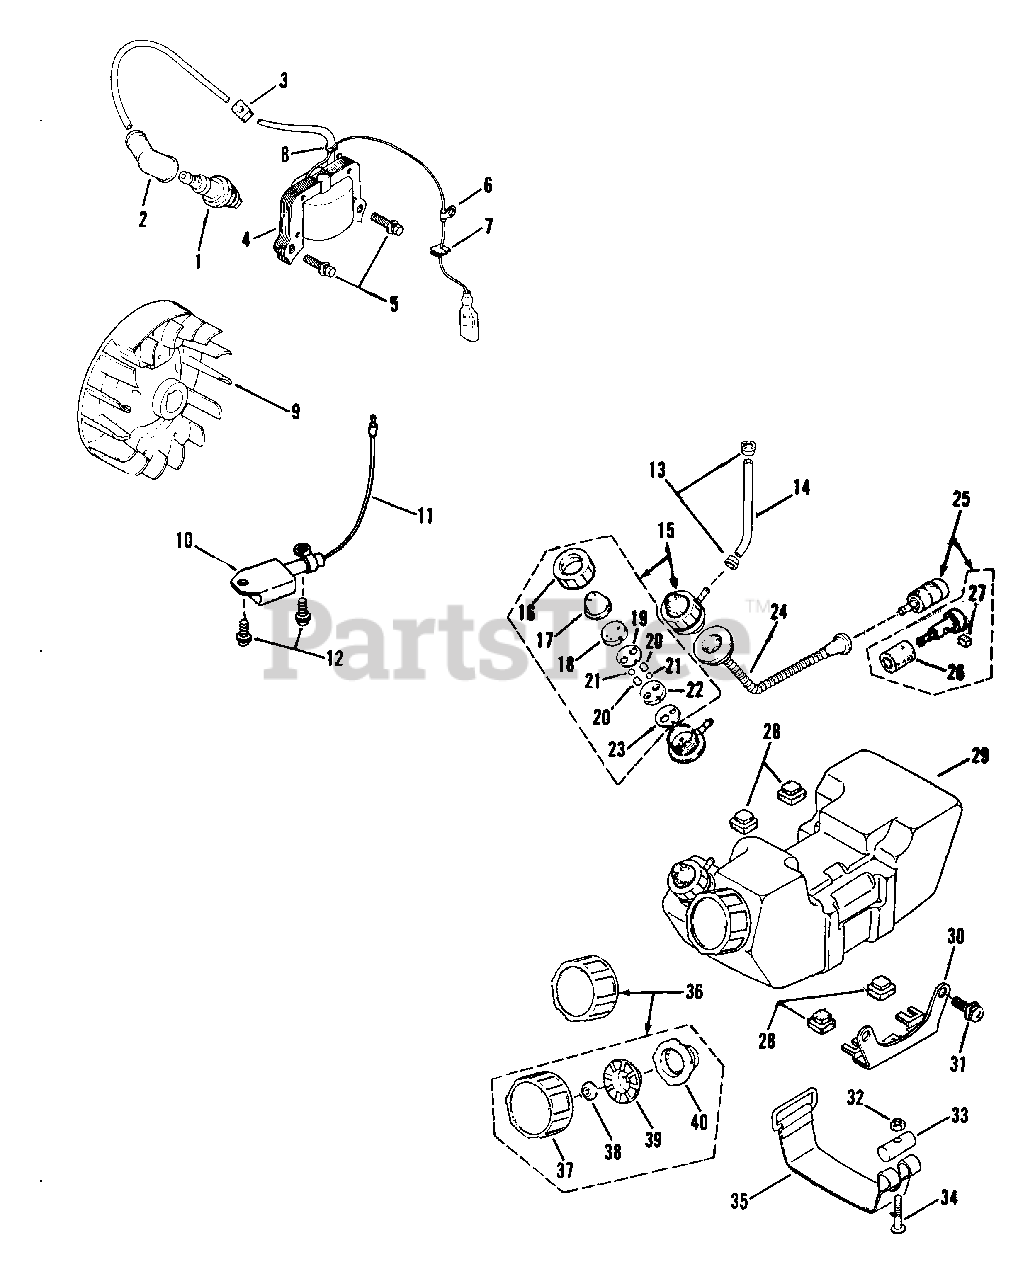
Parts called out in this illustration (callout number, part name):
1	SPARK PLUG (NGK:BM-6A)
2	BOOT, Spark Plug
3	BUSHING, Dust Seal
4	COIL, Ignition
7	BUSHING, Dust Seal
8	BAND
9	FLYWHEEL
10	MTI Unit
11	WIRE, Lead
13	CLIP, Fuel Tube
14	TUBE, Fuel
15	PRIMER PUMP ASSM'Y.
16	CAP, Pump
17	CAP, Rubber
18	SEAT, Valve B
22	SEAT, Valve A
24	HOSE, Fuel
25	FILTER ASSM'Y.,Fuel
29	TANK ASSM'Y.,Fuel
30	HANGER, Tank
31	SCREW, Hanger
33	BAR, Band Support
35	BAND, Tank
36	CAP ASSM'Y.,Fuel
37	CAP, Fuel
40	GASKET
